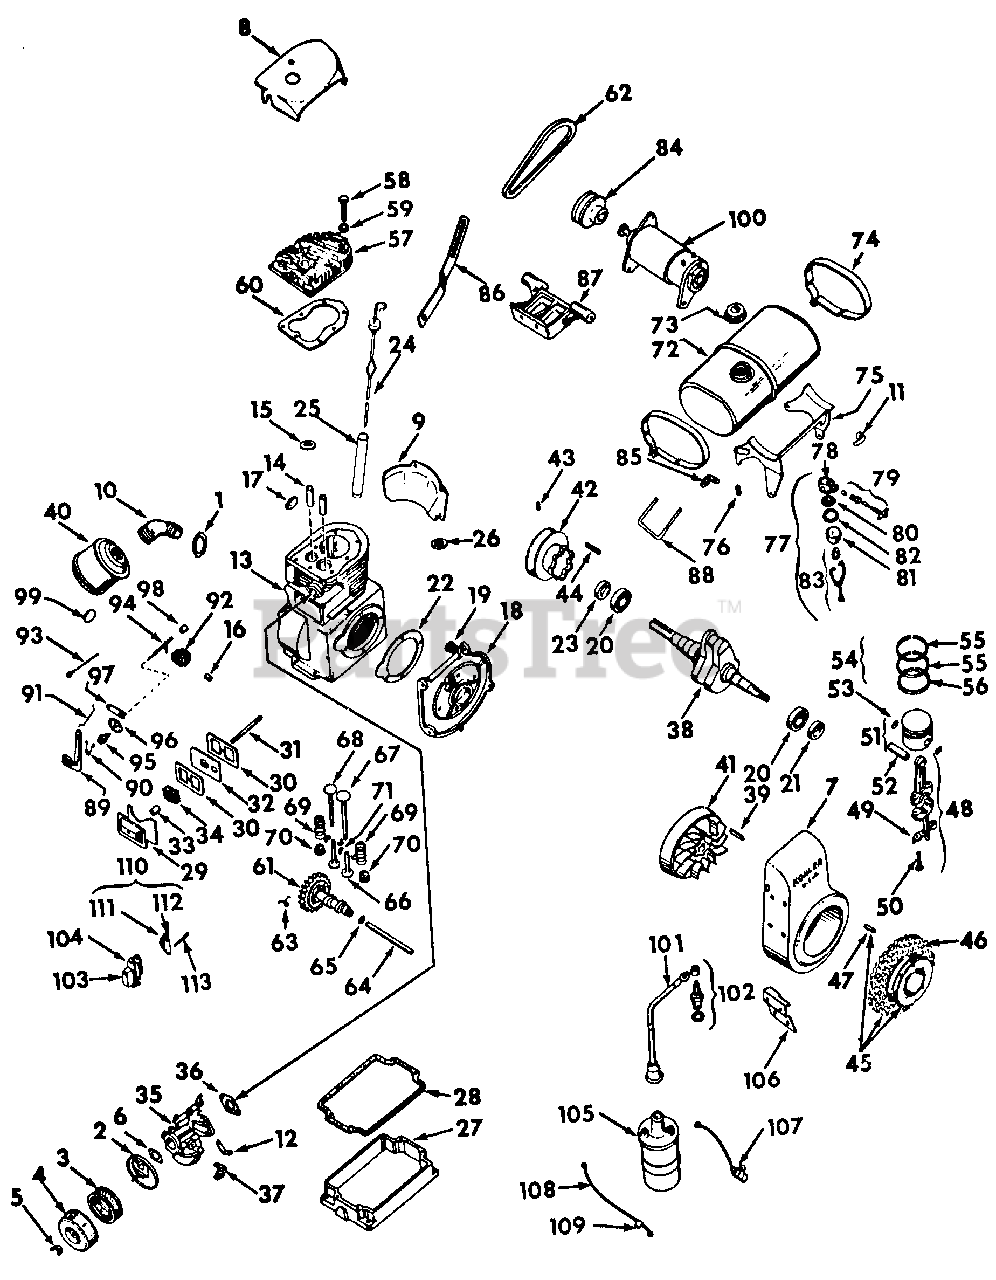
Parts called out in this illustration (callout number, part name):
1	Nut, Exhaust Muffler Elbow Lock
2	Base, Air Cleaner
3	Element, Air Cleaner Filter
4	Cover, Air Cleaner
5	Nut, Air Cleaner Wing
6	Gasket, Air Cleaner
7	Housing Assy, Blower
8	Baffle, Cylinder Head Air
9	Baffle, Cylinder Air
10	Elbow, Exhaust Muffler
11	Clip, Choke Cable
12	Bracket, Choke
13	Crankcase Assy
14	Guide, Valve
15	Insert, Exhaust Valve
16	Shaft, Governor
17	Plug, 1-1/8 Expansion
18	Plate, Crankcase Brg
19	Plug, 5/8 Button, Crankcase Bearing Plate
20	Bearing, Crankcase Ball
21	Seal, Crankcase Brg Plate Oil
22	Gasket, Brg Plate
23	Seal, Crankcase Oil
25	Tube, Oil Fill
26	Insert, Intake Valve
27	Base, Oil Pan
28	Gasket, Oil Pan Base
29	Cover w/Filter, Breather
30	Gasket, Breather
31	Stud, Breather Cover
32	Plate Assy, Breather
33	Seal, Breather
34	Filter, Breather
35	Carburetor Assy
36	Gasket, Carburetor
37	Connector, Fuel Tank
38	Crankshaft
39	Key, Crankshaft
40	Muffler, Exhaust
42	Pulley w/Clutch Drive Plate, Flywheel
43	Screw, Flywheel Pulley Set
44	Key, 1/4 X 7/8 Sq Parallel
45	Cup Assy, Flywheel Drive
46	Screen, Drive Cup Grass
47	Pin, Flywheel Drive Cup
48	Rod Assy, Connecting, Std
49	Lock, Connecting Rod Screw
50	Screw, Connecting Rod
51	Piston Assy, Std
52	Pin, Piston, Std
53	Retainer, Piston Pin
54	Ring Set, Piston, Std
55	Ring, Compression
56	Ring, Oil Control
57	Head, Cylinder
58	Screw, Cylinder Head
59	Washer, Cylinder Head
60	Gasket, Cylinder Head
61	Camshaft Assy
62	Belt, Motor Generator Drive
63	Spring, Camshaft Actuating
64	Pin, Camshaft
65	Shim, Camshaft, .005
66	Tappet, Valve
67	Valve, Intake
68	Valve, Exhaust
69	Spring, Valve
70	Retainer, Valve Spring
71	Key, Valve Spring Retainer
72	Tank Assy, Fuel w/Filler Cap
73	Cap, Fuel Filler
74	Strap, Fuel Tank
75	Bracket Assy, Fuel Tank
76	Nipple, 1/8 X 3/4 C-Z Pipe
77	Filter Assy, Fuel
78	Body, Fuel Filter
79	Valve Assy, Needle
80	Screen, Filter
81	Bowl, Fuel Filter Glass
82	Gasket, Fuel Filter Bowl
83	Bail Assy, Fuel Filter Bowl
84	Pulley, Motor Generator Drive
85	Connector, Fuel Tank
86	Brace, Motor Generator Adjusting
87	Bracket, Motor Generator Mounting
88	Line, Fuel Filter to Carburetor Fuel
89	Lever, Governor
90	Spring, Governor
91	Linkage, Governor
92	Gear Assy, Governor
93	Pin, Governor Stop
94	Shaft Assy, Governor Cross
95	Bushing, Cross Shaft
96	Disc, Governor Regulating
97	Bracket, Speed Control
98	Bearing, Cross Shaft Needle
99	Plug, 1-1/8 Expansion
100	Motor Generator
101	Kit, Hi-Tension Spark Plug, Cable Lead
102	Plug, Spark (Champion)
103	Gasket, Breaker Cover
104	Cover, Breaker
105	Coil, Ignition
106	Bracket, Coil Mounting
107	Condenser, Ignition Coil
108	Cable Assy, Condenser to Breaker
109	Clip, Condenser to Breaker Cable
110	Bracket & Breaker Assy
111	Breaker Point Set
112	Bracket, Point Breaker
113	Rod, Breaker
